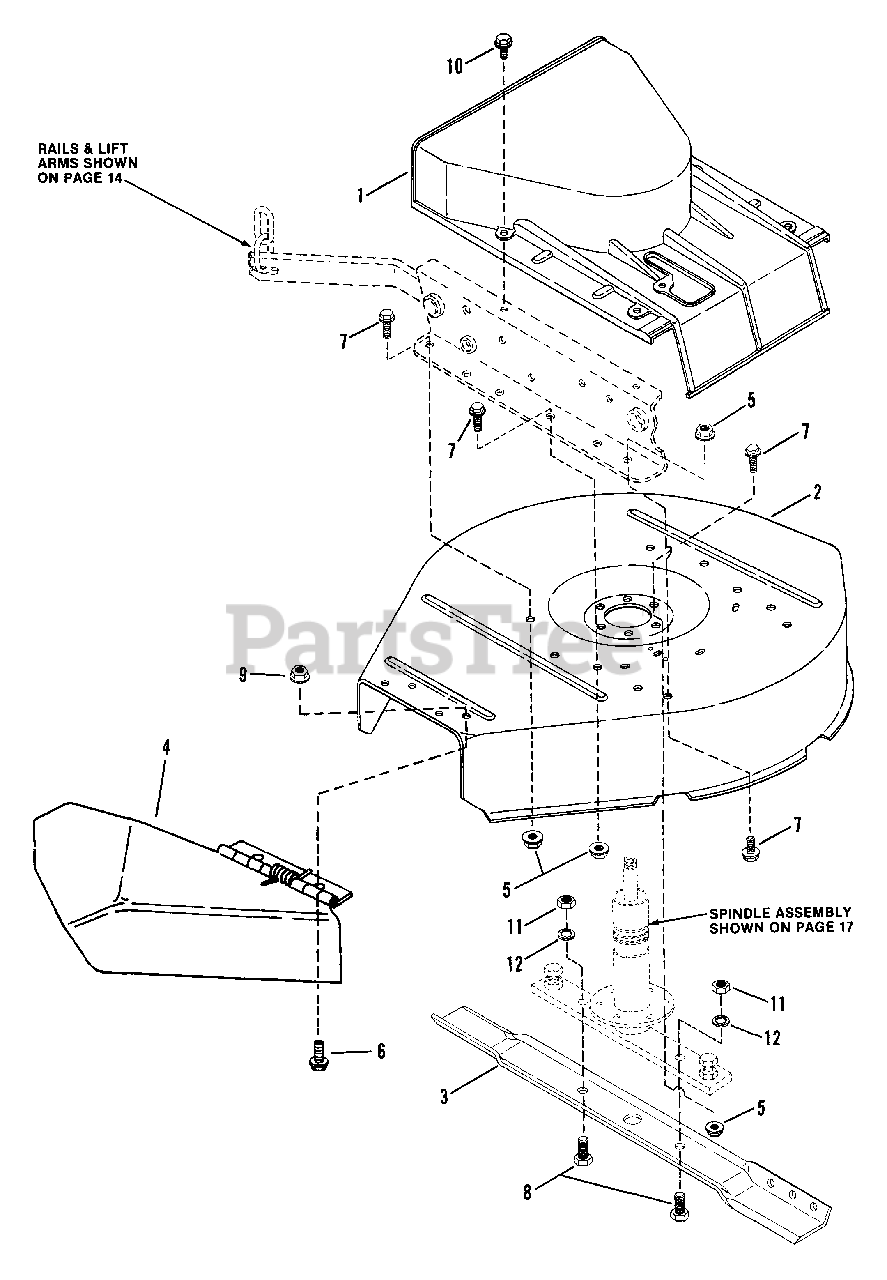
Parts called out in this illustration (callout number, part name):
1	COVER, Spindle & Belt
2	DECK, 30"
3	BLADE
4	DEFLECTOR, Discharge
5	NUT, 3/8-16 Hex Flange Lock
6	BOLT, 5/16-18 x 1/2" Flange Lock
7	BOLT, 3/8-16 x 3/4" Flange Lock
8	SCREW, 1/2-20 x 1" Hex Head Cap
9	NUT, 5/16-18 Hex Flange Lock
10	SCREW, 1/4-20 x 5/8" Self-Tapping
11	NUT, 1/2-20 Hex Jam
12	WASHER, 1/2 Internal Tooth Lock
